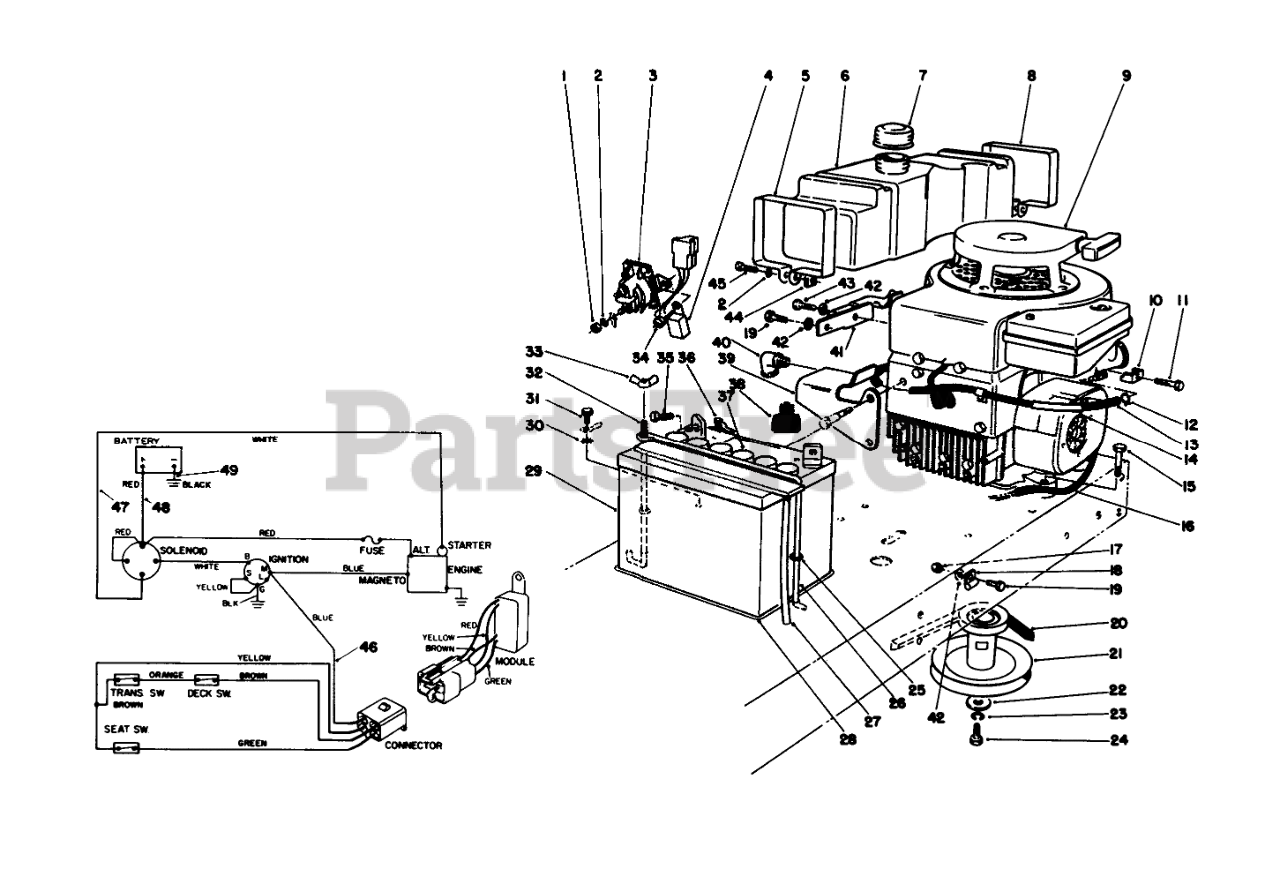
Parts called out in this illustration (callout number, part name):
1	NUT-JAM
2	WASHER-LOCK
3	SOLENOID
4	INTERLOCK MODULE
5	Retainer-Tank Front
6	TANK-5 QT GAS
7	GAS CAP ASM
8	Retainer-Rear
10	CLAMP-CASING
11	SCREW W ENGINE
12	CLAMP-HOSE
13	HOSE-FUEL
14	SUPPORT-FUEL LINE
15	SCREW-HH
16	HEAT SHRINK TUBING
17	NUT-LOCK, NI
18	CLAMP
19	SCREW-HH
20	V-BELT, TRACTION
21	PULLEY
22	WASHER-FLAT
23	WASHER-LOCK
24	SCREW-HH
25	O-RING
26	HOLDDOWN-BATTERY
27	TUBE-BATT DRAIN/80-2600
28	PAD-SKID, ANTI
29	Battery
30	WASHER-LOCK, INTERNAL
31	SCREW-HHF
32	POST-BATTERY
33	NUT-WING
34	NUT-LOCK, CONE
35	SCREW-HH
36	NUT-WING
37	CAP-BATTERY
38	BOOT-TERMINAL
39	FRT TANK MTG BRKT B
40	ELBOW-STREET, 90 DEG
41	REAR TANK MTG BRKT B
42	WASHER-PLAIN
43	SCREW-HH
44	NUT-SQUARE
45	SCREW-HSH
46	WIRE HARNESS
47	STARTER WIRE HARNESS
48	WIRE ASM
49	WIRE ASM(BATT/GRD.
